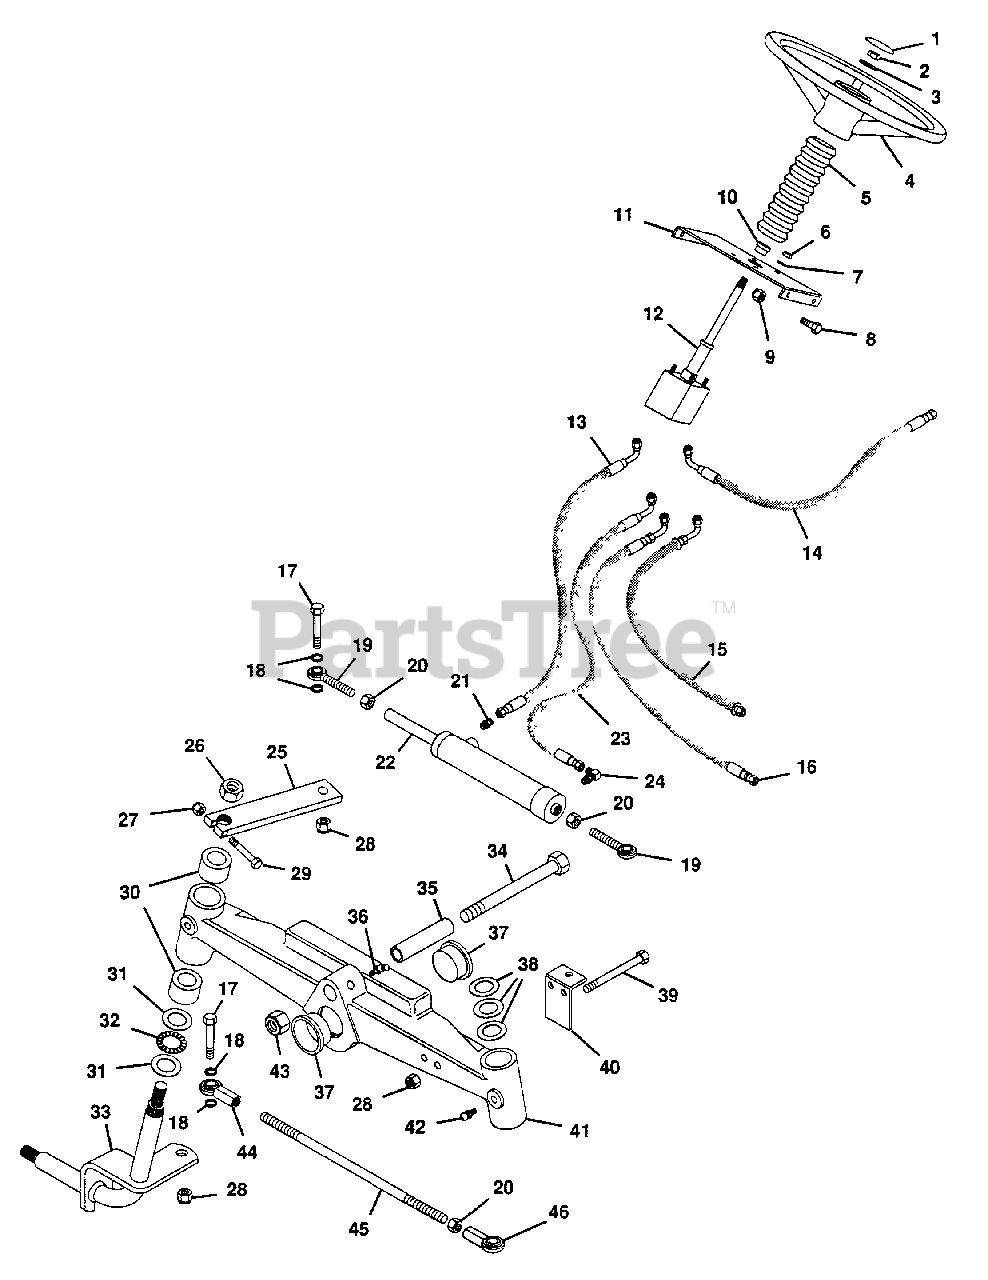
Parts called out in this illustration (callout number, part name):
1	CAP, STEERING WHEEL
2	NUT, JAM 5/8-11 HEX
3	WASHER, FLAT .656X1.312X.095
4	WHEEL, STEERING
5	BELLOWS, STEERING WHEEL
6	NUT, HEX 5/16-24
7	WASHER, LOCK 5/16 REG.
8	BOLT, HEX 5/16-18X.75
9	NUT, LOCK 5/16-18
10	BUSH., FLG. .764X1.47X.560 NY.
11	BRACKET, POWER STEERING SUPPORT
12	POWER STEERING UNIT
13	HOSE, PSU TO SC RIGHT
14	HOSE, PSU TO PUMP
15	HOSE, PSU TO OIL FILTER
16	HOSE, PSU TO LIFT VALVE
17	BOLT, HEX 1/2-13X2.00
18	BUSH., ST. .520X.625X.125 STL.
19	ASSEMBLY, ROD END(R.H.)
20	NUT, JAM 1/2-20
21	ADAPTER, P.H. #0503-6-6
22	CYLINDER, STEERING
23	HOSE, PSU TO SC LEFT
24	ADAPTER(P.H. #2503-6-6)
25	ARM, TIE ROD
26	NUT, HEX 5/8-11
27	NUT, LOCK 5/16-24
28	NUT, LOCK 1/2-13
29	BOLT, HEX 5/16-24X1.75
30	BUSH., ST. .885X1.00X1.00 BRZ.
31	RACE, BEARING THRUST
32	BEARING, NEEDLE THRUST
33	WELDMENT, KING PIN(R.H.)
33	WELDMENT, KING PIN(L.H.)
34	BOLT, HEX 3/4-10X4.5
35	TUBE, AXLE PIVOT
36	FITTING, LUBE 45 DEG.
37	CAP, FRONT AXLE
38	WASHER, FLAT .812X1.496X.134
39	BOLT, HEX 1/2-13X3.50
40	BRACKET, STEERING CYLINDER
41	AXLE, STEERING
42	FITTING, LUBE 1/4-28
43	NUT, LOCK 3/4-10
44	ROD END, STEERING L.H.
45	TIE ROD
46	ROD END, STEERING R.H.
NS	KIT, SEALS ROSS STEERING UNIT
